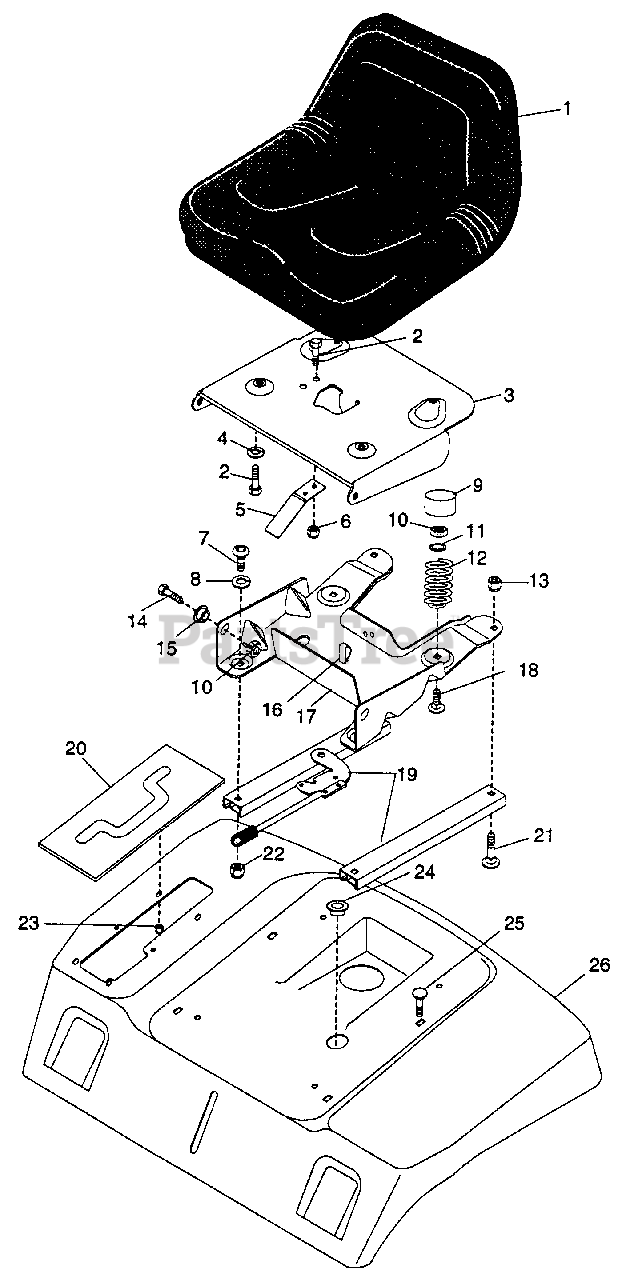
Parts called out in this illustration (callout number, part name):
1	Seat, High Back
2	Blt-Hex .31-18 x .75 Pl Gr 2
3	Seat Pivot Plate
4	Wshr-Lock .312 10 Heavy Pl
5	Spring Plate
6	Nut-Fig .312-18 Pl
7	Scr-Cap Bthd .31-18 x .50
8	Wshr-Lock Ext .313 x .030 Pl
9	Tube Cap
10	Nut-Lk .312-18 Gr A Pl
11	Wshr-Fl-Stl .34 x .68 x .065 Pl
12	Sp-Comp .148 x 1.23 x 2.41 Wld 87
13	Nut-Lk-Nyl .312-18 Pl
14	Blt-Hex .31-18 x .75 Pl Gr 5
15	Bshg Flange .325 x .685 x .465
16	Wire Clip
17	Seat Box
18	Blt-Carr .312-18 x .75
19	Seat Slides Rame Tak 3010-4
21	Blt-Rdhd Sqnk .31-18 x 1.0 Sht Pl
22	Nut-Hex .312-18
23	Nut-Self-Thdng Fits .25 Stud Pl
24	Snap Bushing
25	Blt-Rdgdsqnk .312-18 x .62 Sht Pl
26	Rear Deck F/Tl
